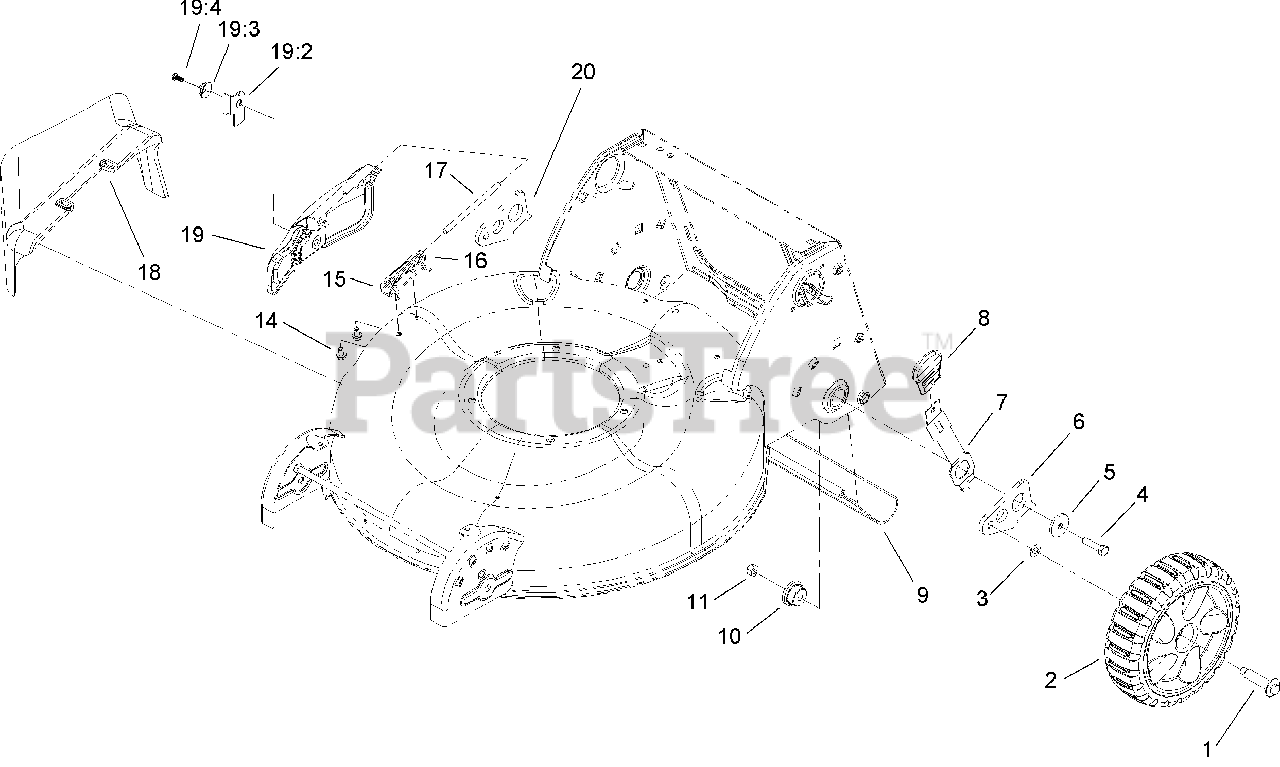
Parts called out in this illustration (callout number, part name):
1	BOLT-SHOULDER
2	8 INCH WHEEL ASM
4	SCREW-HH
5	Washer-Flat
6	ARM-REAR PIVOT, LH
7	ARM-SPRING, REAR
8	KNOB-LEVER, HOC
9	SHIELD-TRAILING
10	Bushing-Mount, HOC
11	NUT-LOCK, NI
14	SCREW-HWH
15	SPRING-TORSION
16	BRACKET-COVER
17	ROD-COVER
18	CHUTE-DISCHARGE, SIDE
19	DISCHARGE DOOR ASM
19:2	LATCH-DOOR
19:3	CAP-DOOR
19:4	SCREW-PLASTITE
20	ARM-REAR PIVOT, RH
